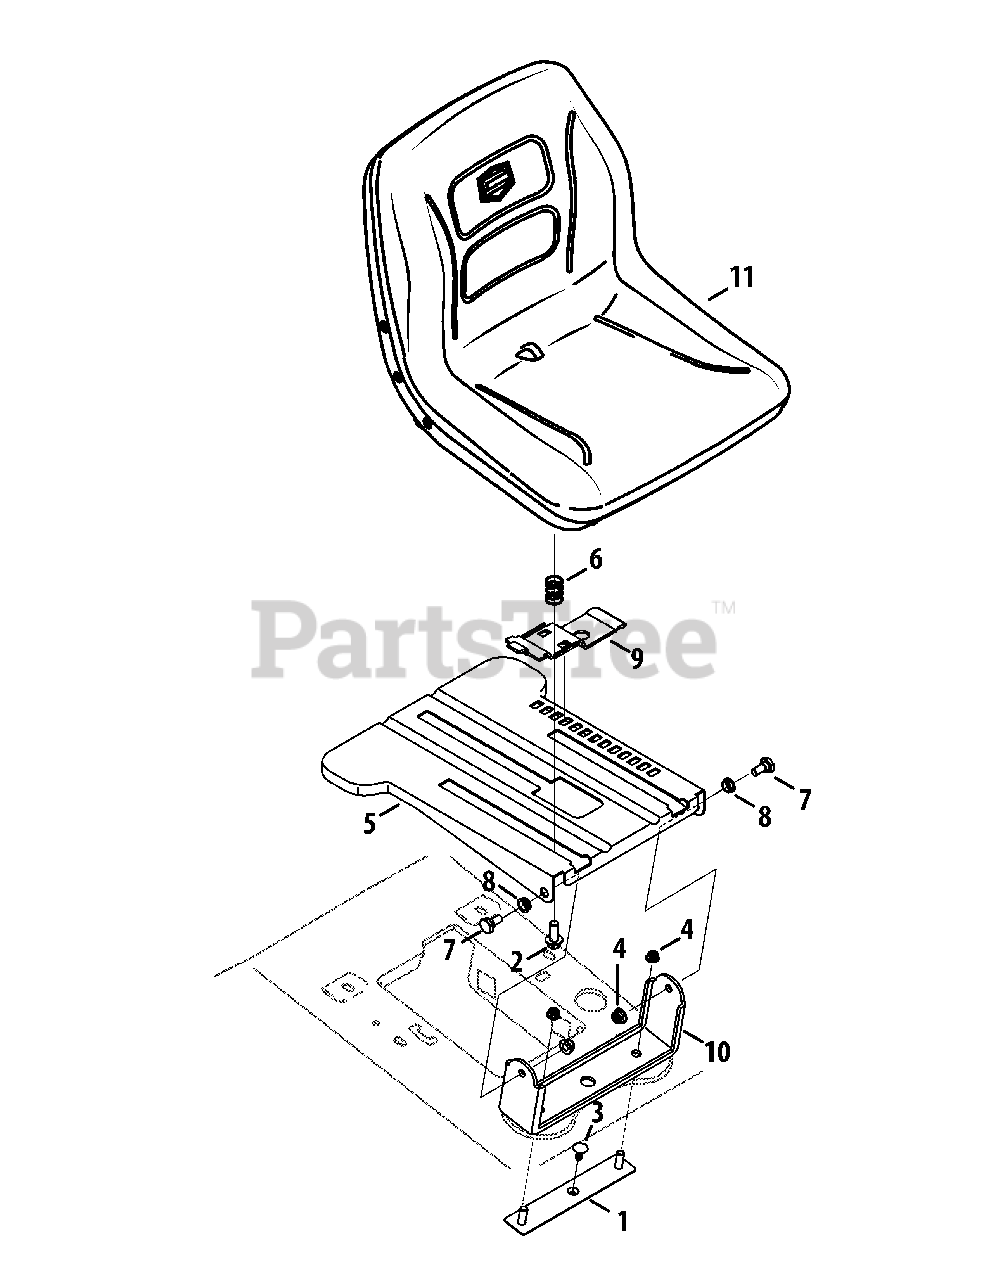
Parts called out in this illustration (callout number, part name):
1	Seat Pivot Plate Assembly
2	Hex Flange Screw, 3/8/16, .875, Gr5
3	Ratchet Clip
4	Nut, Flange Lock, 5/16-18, Grf
5	Bracket, Mounting, Seat
6	Compression Spring, .68 x 1.065 x .055
7	Shoulder Screw, .435 x .178, 5/16 x .56
8	Flange Bearing, .4385 ID
9	Seat Lever
10	Pivot Bracket, Tall
11	Seat
